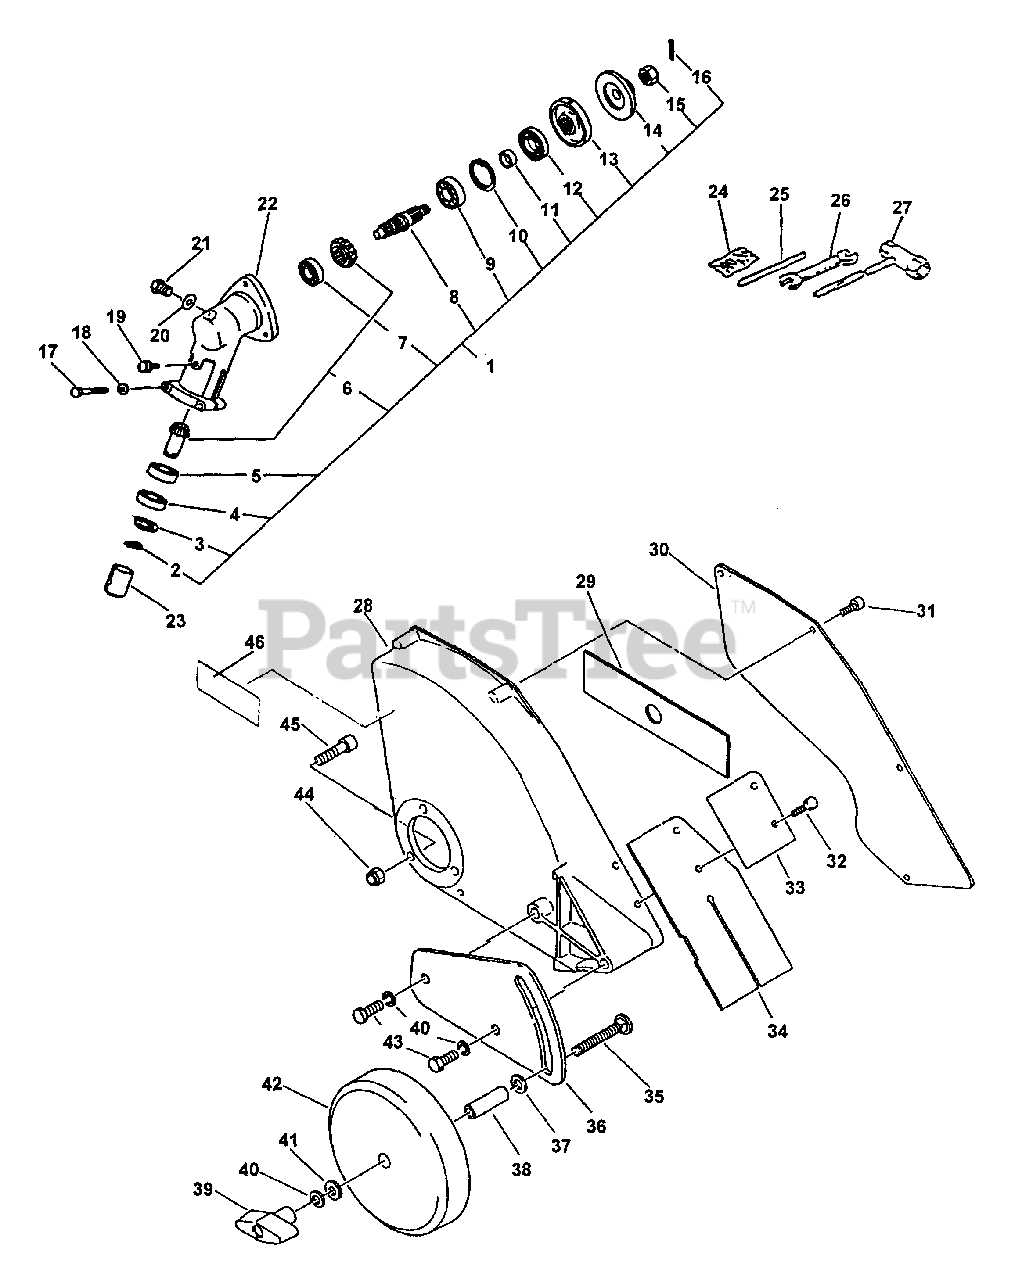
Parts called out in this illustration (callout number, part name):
1	GEAR CASE ASSY
2	RING, RETAINING - 18
3	RING, RETAINING
4	BEARING, BALL - 609
5	BEARING, BALL - 609
6	GEAR SET
7	BEARING, BALL - 629
8	GEAR - SHAFT
9	BEARING, BALL - 6201
10	RING, RETAINING - 20
12	SEAL, OIL
13	ADAPTOR, BLADE - UPPER
14	ADAPTOR, BLADE - LOWER
15	NUT - 10 -- LEFT HAND
16	PIN, SPLIT - 2X22
17	BOLT - 5X30
18	WASHER - 5
19	SCREW - 5X12
21	FITTING, GREASE
22	CASE, GEAR
23	COLLAR
24	PIN, SPLIT - 2X22
25	LOCKING TOOL
26	SPANNER - 8X10mm
27	T-WRENCH - 17X19mm
28	NEW BLADE SHIELD
29	BLADE, EDGER
30	COVER, SHIELD
31	SCREW - 4X12
32	SCREW - 4X14
33	FLAP, DEBRIS
34	FLAP, DEBRIS
35	BOLT - CARRIAGE
36	BRACKET, WHEEL
37	WASHER - 10
38	COLLAR - 12
39	WINGNUT - 5/16-18
40	LOCKWASHER - 8
41	WASHER - 8
42	WHEEL - 6X1.5
43	BOLT - 8X14
44	LOCKNUT - 5
45	SCREW - 5X22
46	LABEL - CAUTION
